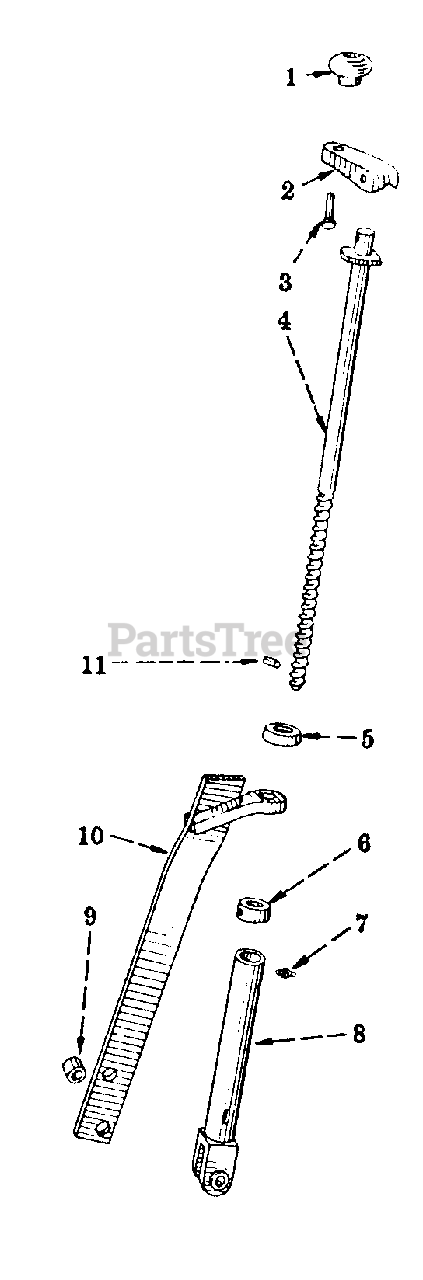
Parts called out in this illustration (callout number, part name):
1	KNOB, DEPTH ADJUSTING SCREW HANDLE
2	HANDLE, DEPTH ADJUSTING SCREW
3	PIN, 1/2 X 2-9/16 ROLL
4	SCREW ASSY, DEPTH ADJUSTING
5	BEARING, THRUST
6	COLLAR, DEPTH ADJUSTING SCREW
7	FITTING, 1/8-27 STR LUB
8	HOUSING, DEPTH ADJUSTING SCREW
9	SPACER, DEPTH ADJUSTING SCREW BRACKET
10	SUPPORT ASSY DEPTH ADJUSTING SCREW
11	PIN, 1/4 X 7/8 ROLL
